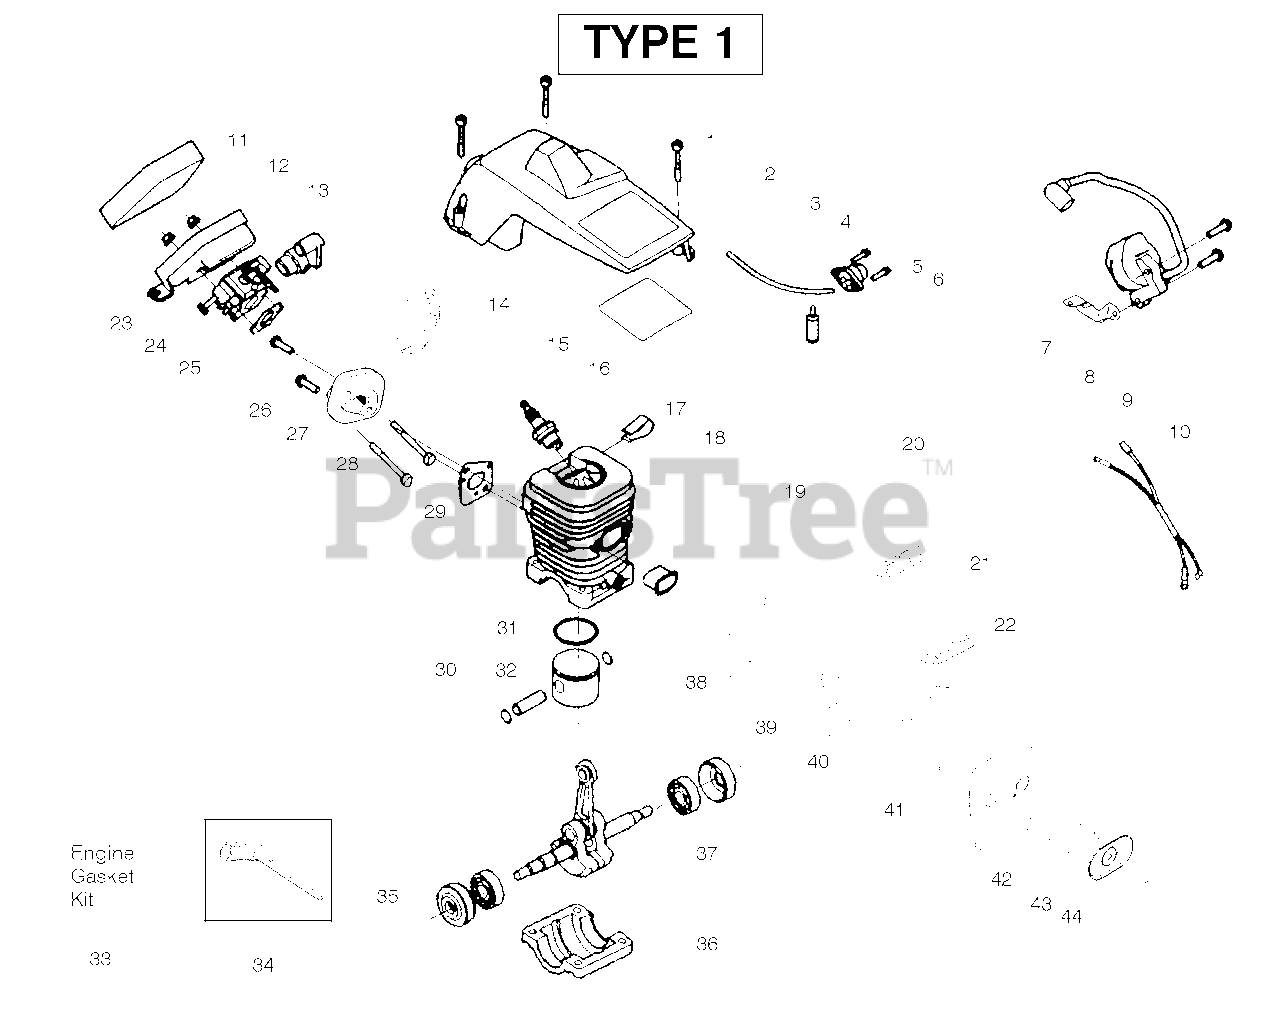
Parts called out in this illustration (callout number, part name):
2	Assy-Cylinder Shield
3	Kit-Fuel Line (Small)
4	Assy- Air Purge
6	Assy-Fuel Pick-up
7	Strap-Ground
8	Ignition Module
10	Assy-Wire Harness
11	Foam- Air Filter
13	Grommet-Carb Adjust
14	Seal-Carb Adapter
15	Reflector-Heat
16	Spark Plug (RCJ-7Y)
17	Clip-High Tension Lead
18	Kit-Cylinder
19	Insulator-Heat
20	Screw-Outlet cover
21	Cover - Outlet
22	Kit-Spark Arrestor
23	Air Filter Housing
24	Kit-Carburetor (WT-599)
24	Kit-Carburetor (W-9A)
25	Gasket-Carb.
27	Carb. Adapter
29	Gasket-Carb Adaptor
30	Kit-Piston
31	Ring-Piston
32	Retainer-Piston Pin
33	Kit-Engine Gasket
34	Bar Wrench
35	Assy-Seal & Bearing
36	Cap-Crankcase
37	Assy-Crankshaft
38	Backplate
39	Guide-Outlet
40	Gasket-Muffler
41	Assy-Muffler
42	Bolt-Muffler
43	Cover-Bolt
44	Nut-Brass
